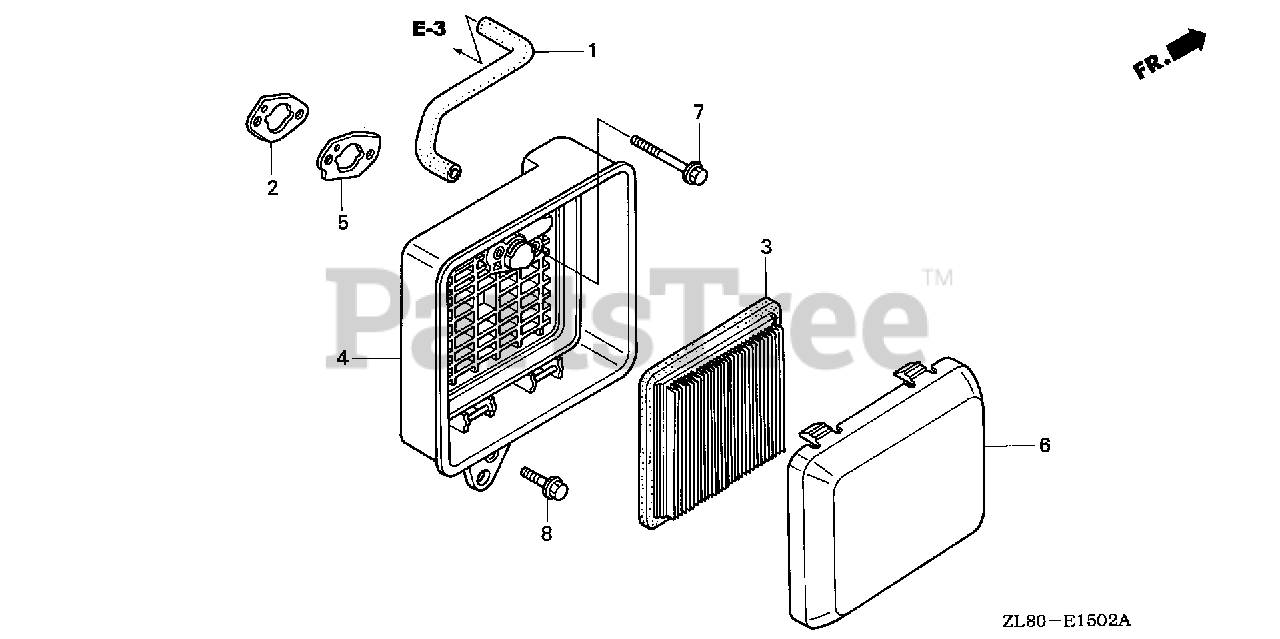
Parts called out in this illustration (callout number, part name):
1	TUBE, BREATHER
2	SPACER, CARBURETOR
3	ELEMENT, AIR CLEANER (TOYO ROKI)
4	CASE ASSY., AIR CLEANER
5	GASKET, AIR CLEANER
6	COVER, AIR CLEANER
7	BOLT, FLANGE (6X86) (CT200)
8	BOLT, FLANGE (6X35) (CT200)
